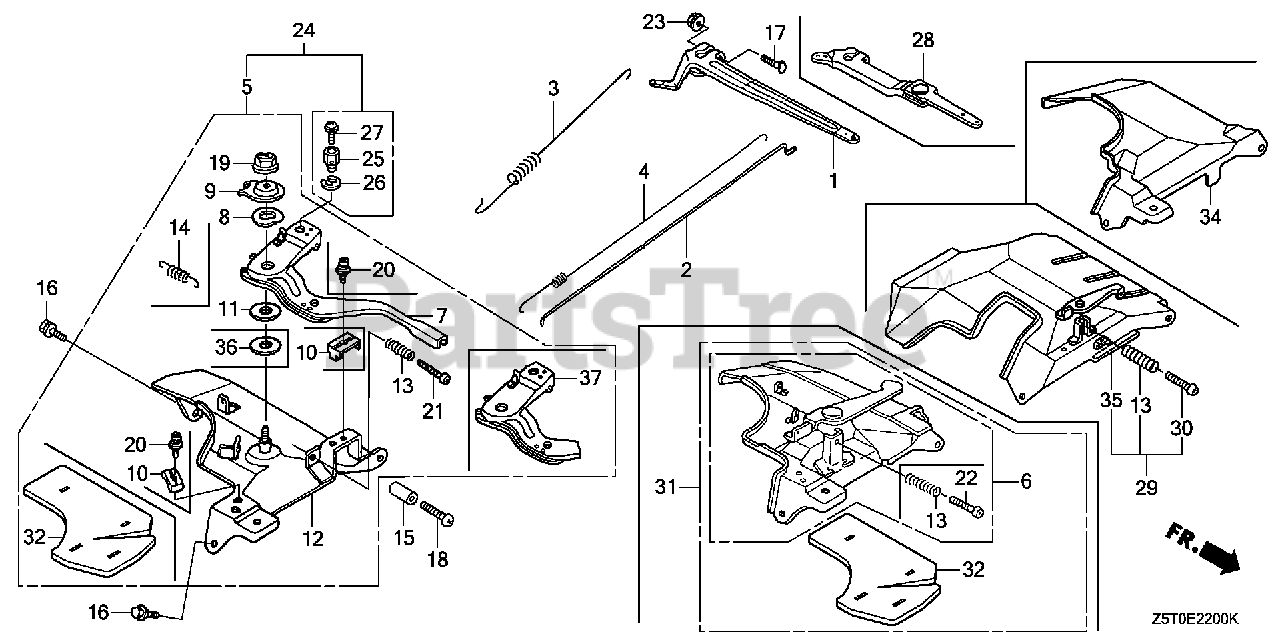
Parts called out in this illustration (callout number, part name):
1	ARM, GOVERNOR
2	ROD, GOVERNOR
3	SPRING, GOVERNOR
4	SPRING, THROTTLE RETURN
5	CONTROL ASSY. (REMOTE)
7	LEVER, CONTROL
8	SPRING, LEVER
9	WASHER, CONTROL LEVER
10	HOLDER, CABLE
11	SPACER, CONTROL LEVER
12	BASE, CONTROL
13	SPRING, CONTROL ADJUSTING Use from Engine SN 2327377.
14	SPRING, CABLE RETURN
16	BOLT, FLANGE (6X12) (CT200)
17	BOLT, GOVERNOR ARM
19	NUT, SELF-LOCK (6MM)
20	SCREW, PAN (5X16)
21	SCREW, PAN (5X32)
23	NUT, FLANGE (6MM)
